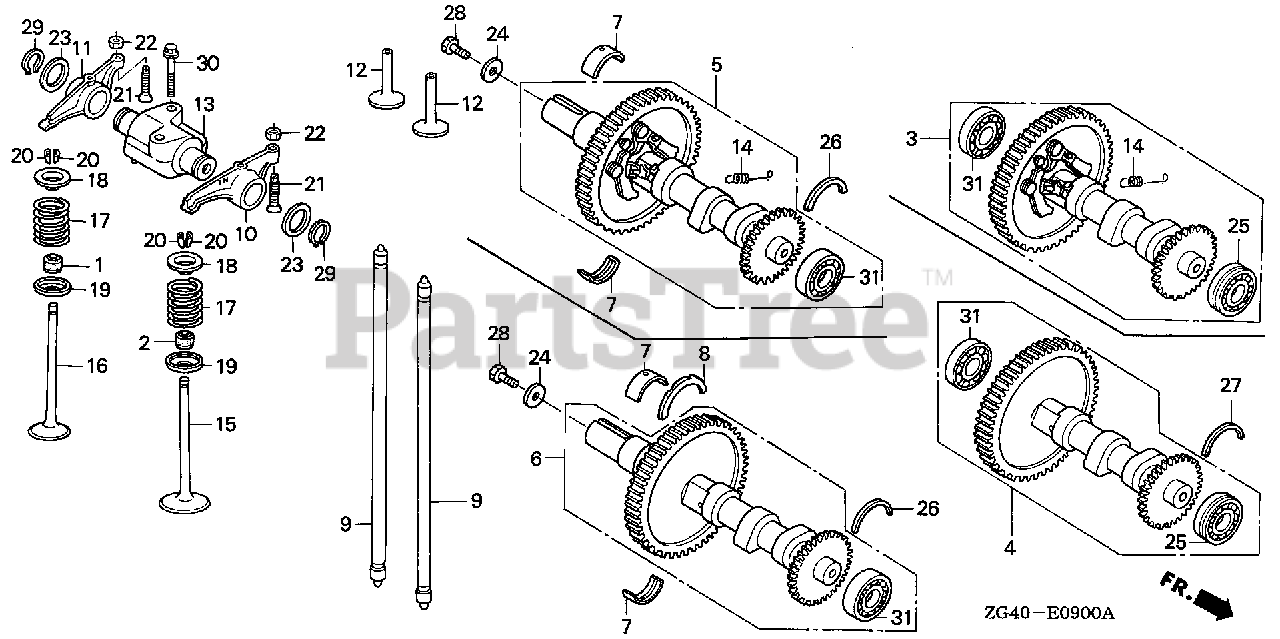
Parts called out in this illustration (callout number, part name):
2	SEAL A, VALVE STEM (ARAI)
3	CAMSHAFT ASSY. (USA)
10	ARM, IN. VALVE ROCKER
11	ARM, EX. VALVE ROCKER
12	LIFTER, VALVE
13	SHAFT, ROCKER ARM
14	SPRING, WEIGHT RETURN
15	VALVE, IN.
16	VALVE, EX.
17	SPRING, VALVE
18	RETAINER, VALVE SPRING
19	SEAT, VALVE SPRING
20	COTTER, VALVE
21	SCREW, TAPPET ADJUSTING
22	NUT, TAPPET ADJUSTING
23	WASHER, THRUST (16MM)
25	BEARING A, SPECIAL BALL (6204) (NTN)
27	SET-RING (470)
29	CIRCLIP, OUTER (16MM)
30	BOLT, FLANGE (6X35)
31	BEARING, RADIAL BALL (6204)
